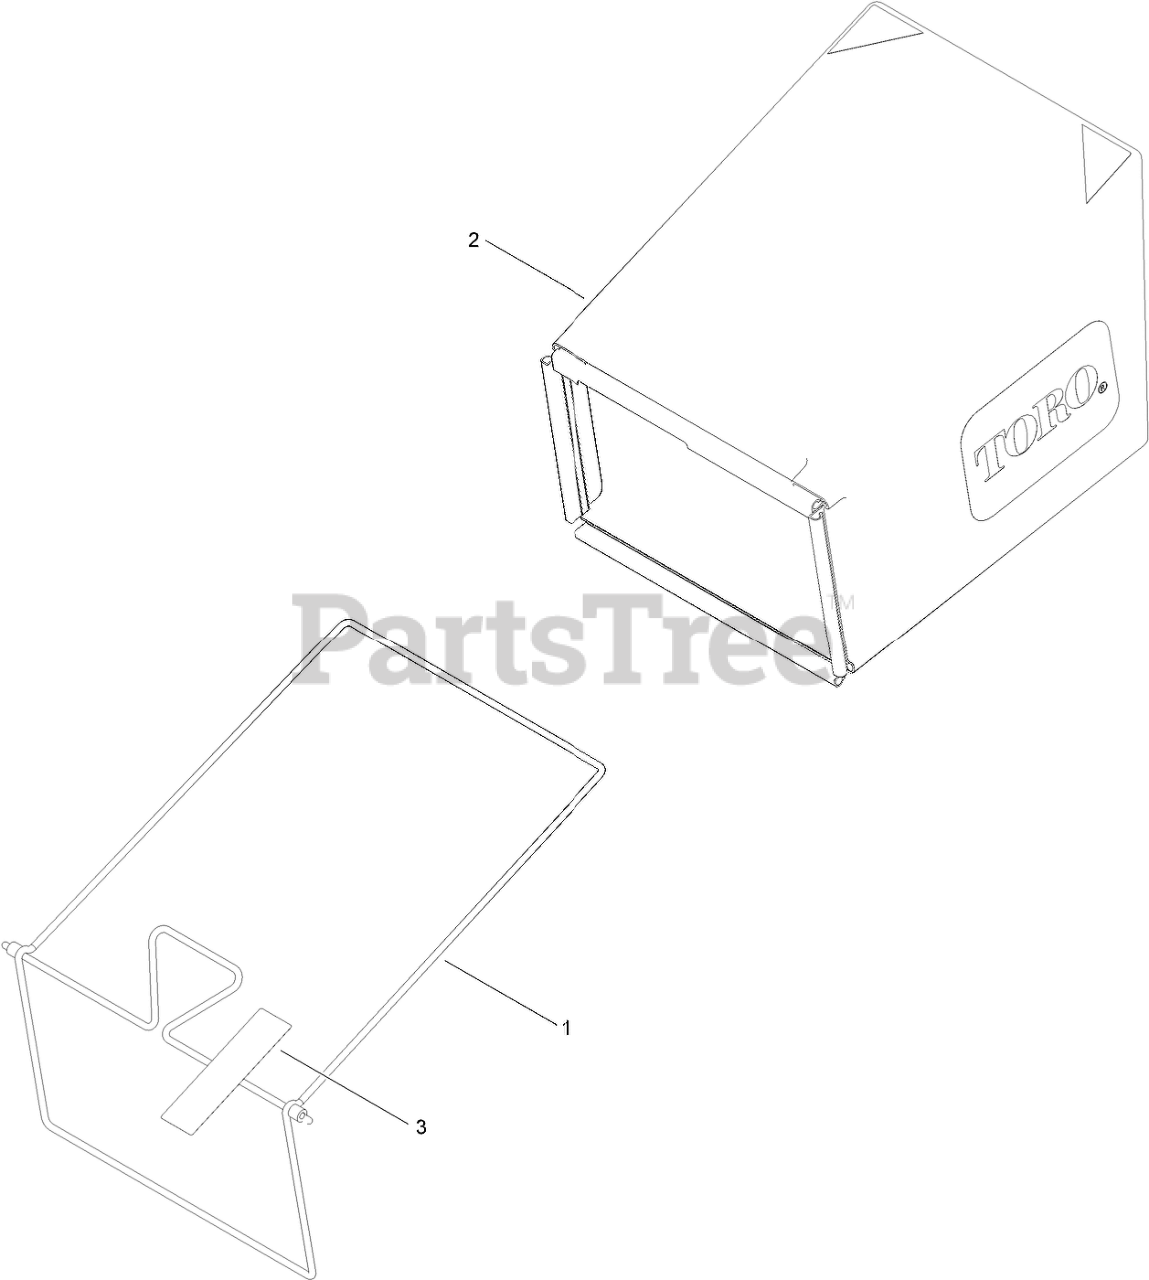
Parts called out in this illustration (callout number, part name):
1	FRAME-BAG
2	BAG-GRASS
3	Decal-Warning
